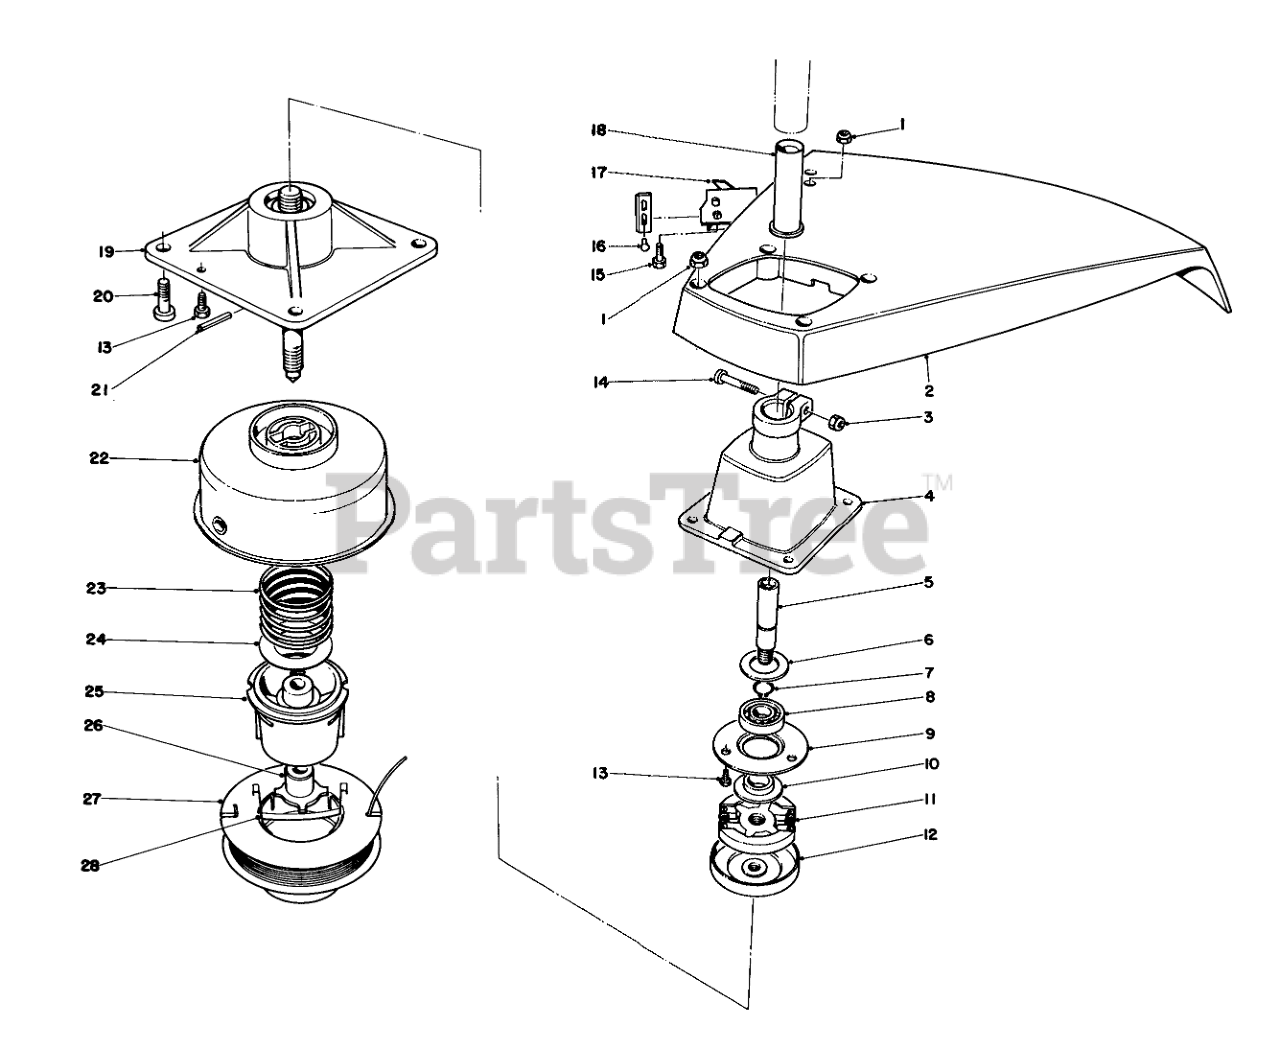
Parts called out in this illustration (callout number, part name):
1	NUT-LOCK, NI
2	Shield 17"
3	NUT-LOCK, NI
4	Clutch Housing
5	SHAFT-UPPER POWER
6	Washer-Flat
7	RING-SNAP
8	Bearing
9	Retainer-Bearing
10	Spacer Clutch
11	Clutch Assembly
12	Drum Assembly
13	SCREW-TAPTITE
14	Screw-Pan Head Machine
15	SCREW-HWH
16	RIVET-BLIND
17	Bracket & Knife Blade Assy.(Incl. Ref. #16)
18	INSERT-POLE END
19	Bearing Housing Assembly
20	SCREW-PPH
21	COIL PIN
22	DRUM/EYELET
23	SPRING COMPRESSION
24	WASHER-FLAT
25	SPOOL CORE
26	DRIVER
27	Empty Spool
28	SADDLE-SPOOL CAP
